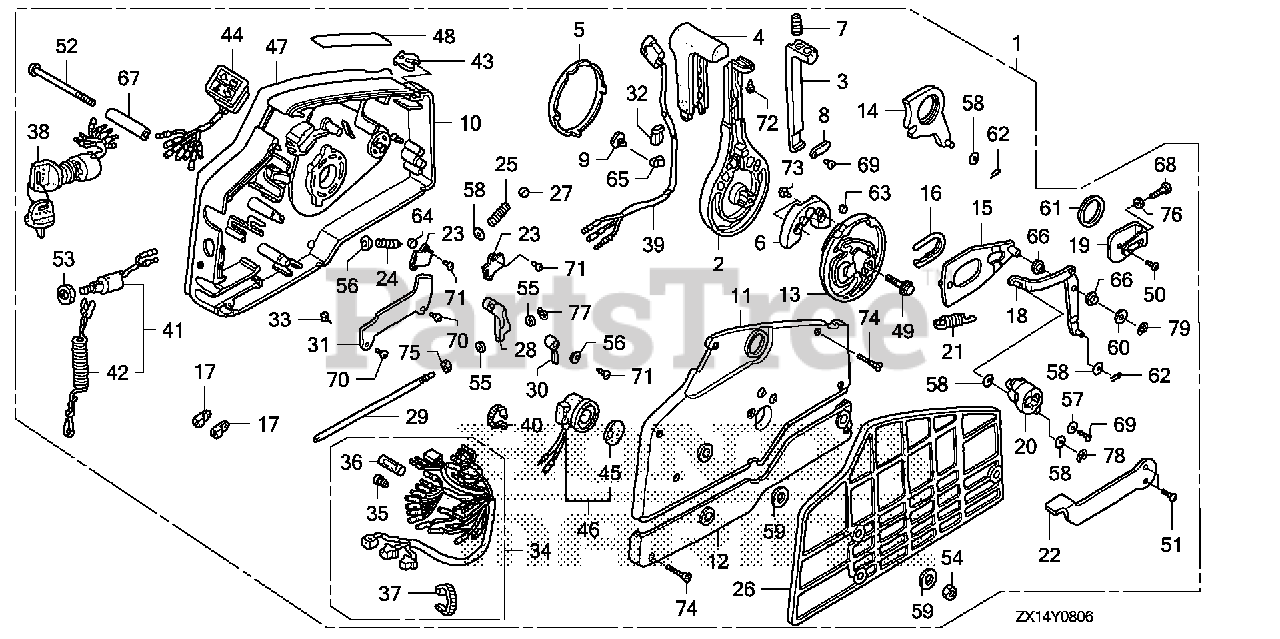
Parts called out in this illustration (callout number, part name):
1	BOX ASSY., REMOTE CONTROL (NHK MEC)
1	BOX ASSY., REMOTE CONTROL (TROLLING CONTROL)(NHK MEC)
2	HANDLE, REMOTE CONTROL
3	LEVER, HANDLE LOCK
4	GRIP, REMOTE CONTROL HANDLE
5	CAP, HANDLE
6	BLOCK, NEUTRAL LOCK
7	SPRING, REMOTE CONTROL HANDLE
8	PLATE, LEVER SETTING
9	CLAMP, HARNESS
10	HOUSING, REMOTE CONTROL BOX (A)
11	HOUSING, REMOTE CONTROL BOX (B)
12	HOUSING, REMOTE CONTROL BOX (C)
13	WHEEL, CONTROL
14	ARM, SHIFT LINK
15	PLATE, SLIDING
16	COLLAR, SLIDING PLATE
17	PIVOT, SHIFT
18	ARM, LINK JOINT
19	BRACKET, LINK JOINT
20	WHEEL, ACCELERATOR
21	SPRING, ACCELERATOR WHEEL
22	LEVER, IDLE
23	PLATE, SPRING SETTING
24	SPRING, SHIFT CLICK
25	SPRING, CHOKE RETURN
26	SPACER, REMOTE CONTROL BOX
27	SPACER, CLICK SPRING
28	BLOCK, THROTTLE FRICTION
29	BOLT, FRICTION
30	SPACER, NEUTRAL SWITCH
31	CLAMP, POWER TILT CORD
32	PIPE, HARNESS GUIDE
33	SPACER, CABLE CLAMP
34	CABLE ASSY., REMOTE CONTROL (B)
35	PLUG, CONNECTOR (INNER)
36	PLUG, CONNECTOR (OUTER)
37	TIE, CABLE (2.4X92) (NATURAL)
38	SWITCH ASSY., COMBINATION
39	SWITCH ASSY., POWER TRIM-TILT
40	BAND (BLACK 3.5X140)
41	SWITCH ASSY., EMERGENCY STOP
42	WIRE, EMERGENCY
43	CLIP, EMERGENCY LOCK
44	LAMP ASSY., INDICATION
45	PLATE, TURN SIGNAL BUZZER
46	BUZZER, WARNING
47	PLATE, REMOTE CONTROL (COUTION COLOR=RED & YELLOW)
48	MARK, FAST IDLE
49	BOLT, FLANGE (8X35)
50	SCREW, PAN (6X10)
51	SCREW, FLAT (5X12)
52	SCREW (6X95)
53	NUT, HEX. (16MM)
54	NUT, HEX. (6MM)
55	WASHER, PLAIN (4MM)
56	WASHER, PLAIN (5MM)
57	WASHER, PLAIN (5MM)
58	WASHER, PLAIN (6MM)
59	WASHER (6MM)
60	WASHER, PLAIN (8MM)
61	WASHER (28MM)
62	PIN, LOCK (6MM)
63	PIN (6X6)
64	ROLLER, CLICK
65	CLIP, WIRE HARNESS (6.3MM)
66	COLLAR, LINK JOINT
67	COLLAR, DISTANCE (6X10X43.5)
68	BOLT, HEX. (5X16)
69	SCREW, PAN (5X10)
70	SCREW, TAPPING (5X8)
71	SCREW, TAPPING (5X10)
72	SCREW, TAPPING (5X12)
73	SCREW, TAPPING (6X16)
74	SCREW, TAPPING (5X25)
75	NUT, HEX. (6MM)
76	NUT, HEX. (5MM)
77	E-RING (3MM)
78	E-RING (4MM)
79	E-RING (7MM)
